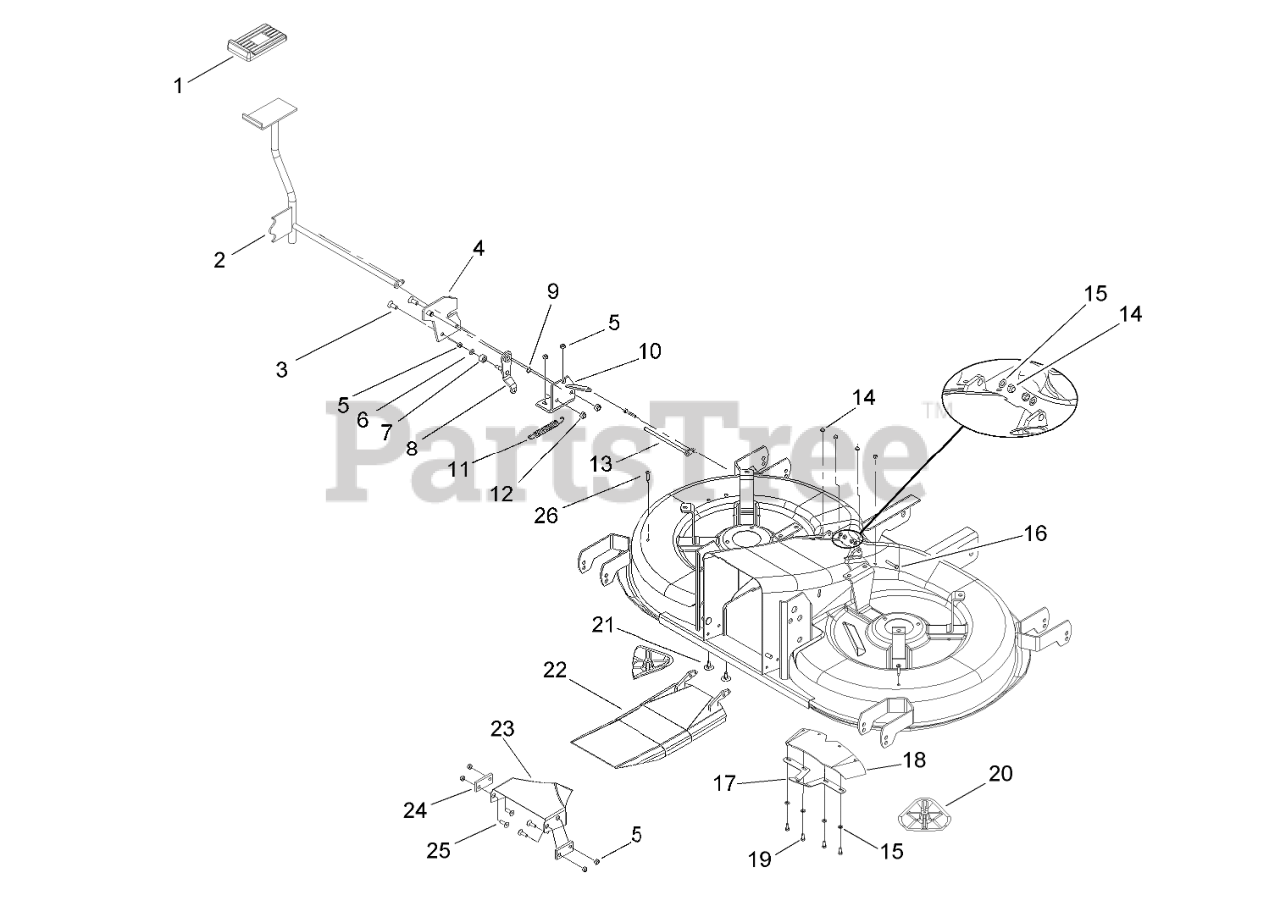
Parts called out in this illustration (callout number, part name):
1	Cover-Lever, FOOT
2	Lever-Foot
3	SCREW-HSFH
4	Plate-Stop
5	NUT-LOCK
6	WASHER-FLAT
7	Roller
8	Lever-Spring
9	RING-LOCKING
10	Bracket-Mounting
11	Spring
12	NUT
13	Rod-Door, Mulch
14	NUT-LOCK
15	WASHER
18	Gasket-Door, Mulch
19	Screw-HH
20	Kicker
21	SCREW-CARR
22	DOOR-MULCH
23	Baffle-Center
24	PLATE-BAFFLE, CENTER
26	SCREW-TAP, PPH
